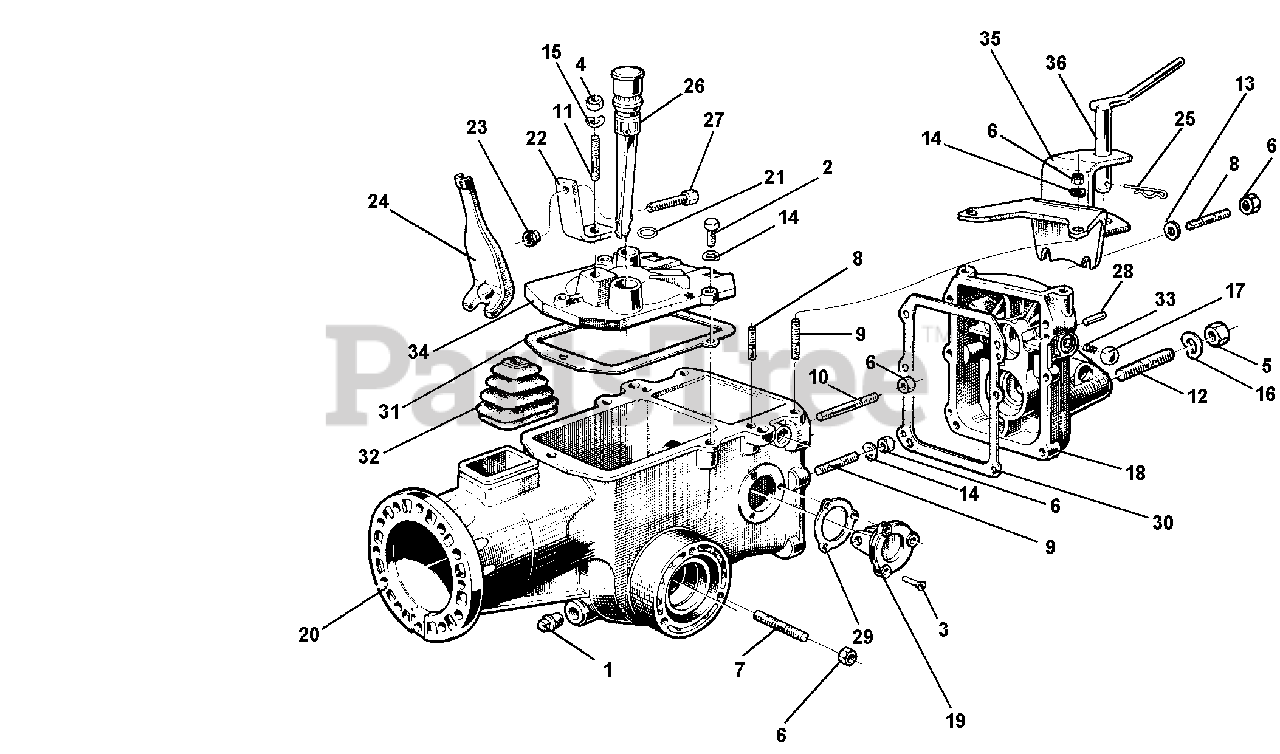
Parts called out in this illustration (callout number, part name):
1	PLUG 1/4 GAS
2	SCREW TE M8 X 30
3	SCREW TSV M6 X 16 UNI 260-5S
5	NUT M12 X 1.25 UNI 5587 6S
6	NUT, SELF LOCKING M8
7	STUD M8 X 46 X 20 X 12
8	STUD M8 X 38 X 14 X 20
9	STUD M8 X 46 X 16 X 16
10	STUD M8 X 58 X 16 X 16
11	STUD M10 X 37 X 19 X 15 8G
12	ST.56XM12X1.25X26XM12X22 8G
13	WASHER, FLAT 8.4
14	WASHER, LOCK 8.4
15	WASHER, LOCK 10.5
16	WASHER, LOCK 13
17	BALL 15/32 RIV RB-11.906
18	HOUSING COVER
19	FLANGE, REVERSE SPEED
20	CASING 5 SPEEDS GEARBOX
21	RUBBER RING
22	BRACKET CLUTCH CONTRAST
23	STOP RING NUT
24	CLUTCH LEVER
26	CAP, WITH MEASURING ROD
27	SCREW, ADJUSTING M8
28	PARALLEL PIN D 6 X 20
30	GASKET, COVER
31	GASKET, COVER
34	COVER DIFFERENTIAL
35	TOW COUPLING
